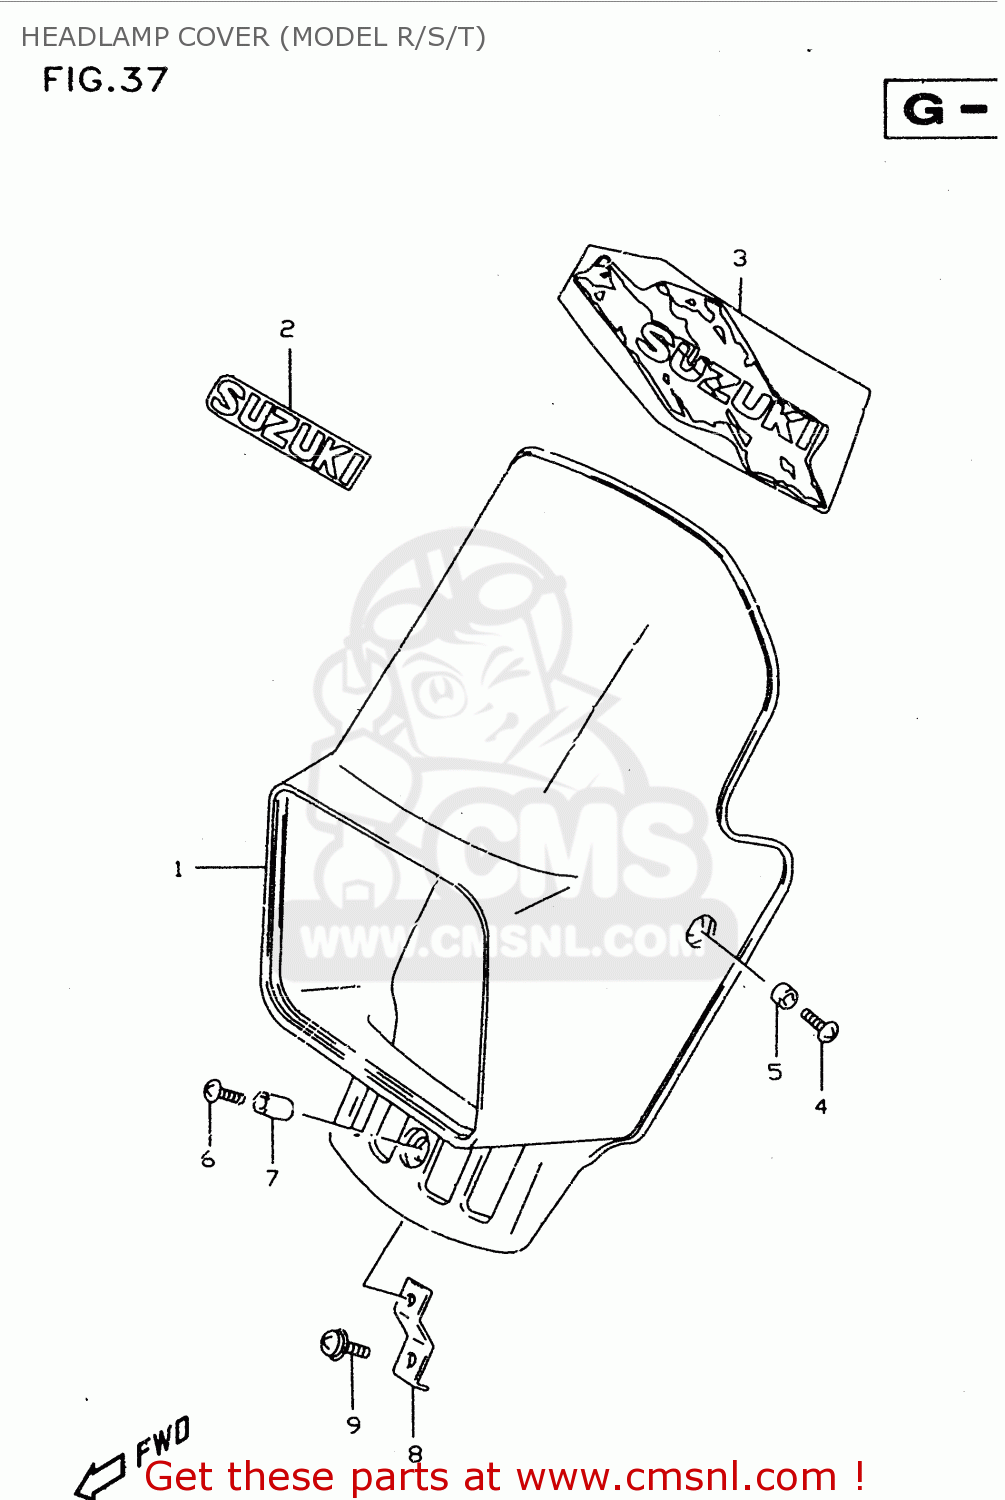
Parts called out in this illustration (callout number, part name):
1	COVER,HEADLAMP
2	EMBLEM,HEADLAMP COVER
3	TAPE,HEADLAMP COVER
4	SCREW 6X12
5	SPACER (6.1X8X3.5)
6	SCREW
7	SPACER (6.1X8X12)
8	PLATE,HEADLAMP COVER
9	SCREW
